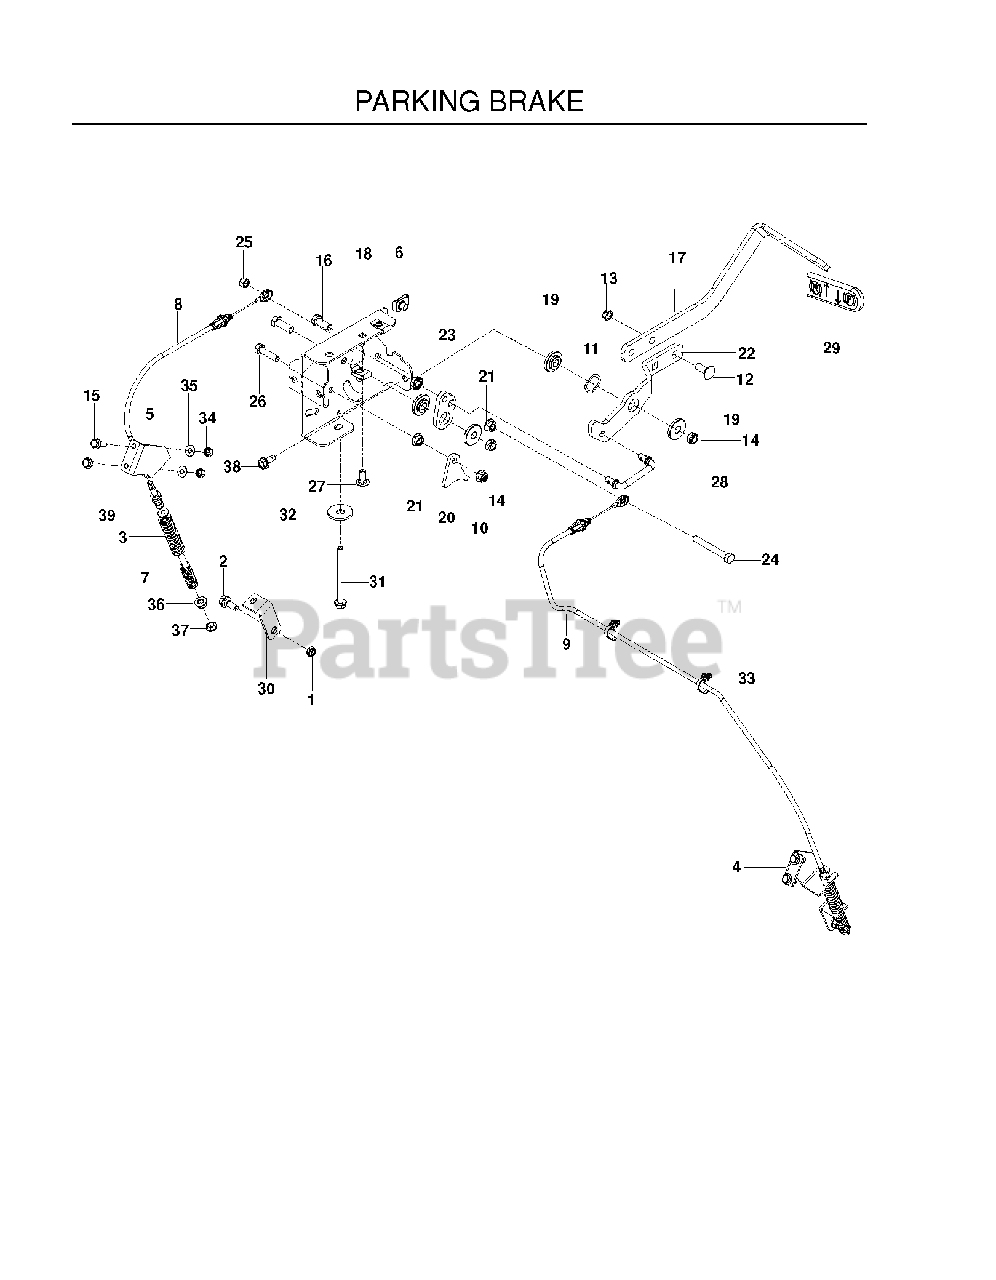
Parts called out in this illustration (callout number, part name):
1	5/16-18 THIN PROF NY
2	BOLT, SHOULDER
3	SPRING, RETURN
4	BRKT, BRAKE RT, BLK
5	BRKT, BRAKE LT, BLK
6	U-CLIP 5/16-18 NUT RETAINER
7	SPRING, ENGAGEMENT
8	RP_CABLE, BRAKE, SHORT
9	RP_CABLE, BRAKE, LONG
10	5/16-18 NYLOC FLANGE NUT
11	WASHER, .825 X 1.087, WAVE
12	RHSNB 3/8C X 1
13	NUT 3/8-16 HEX FLG NYLOC ZD
14	NUT HEX 3/8-16 NYLON, THIN
15	HCS 1/4-20X7/8 GR5
16	HCS 3/8-16X1.GRD.5.ZD
17	ARM, BRAKE
18	MOUNT, BRAKE WLDMT
19	BUSHING, BRAKE
20	ACTUATOR, SWITCH
21	NUT 5/16C WHIZ
22	LEVER, BRAKE
23	BELLCRANK, BRAKE
24	HCS 5/16-18 X 2 1/2 TPBLT
25	NUT 5/16 NYLOC
26	HCS 5/16C X 1
27	BOLT 5/16C X 3/4" CARRIAGE
28	LINKAGE, BRAKE
29	GRIP, PARK BRAKE
30	BRKT, BRAKE, BLK
31	HHFS 5/16-18 X 3 3/4
32	WASH USS FLAT 1/2
33	TIE WRAP, 8-3/8", W/CLIP
34	RP_NUT 1/4-20 NYLOC
35	WASHER 1/4 SAE
36	NUT 5/16C WHIZ
37	NUT 5/16-18 HEX JAM ZD
38	BOLT 5/16-18 X 3/4
39	WASHER 3/8 SAE FLAT
